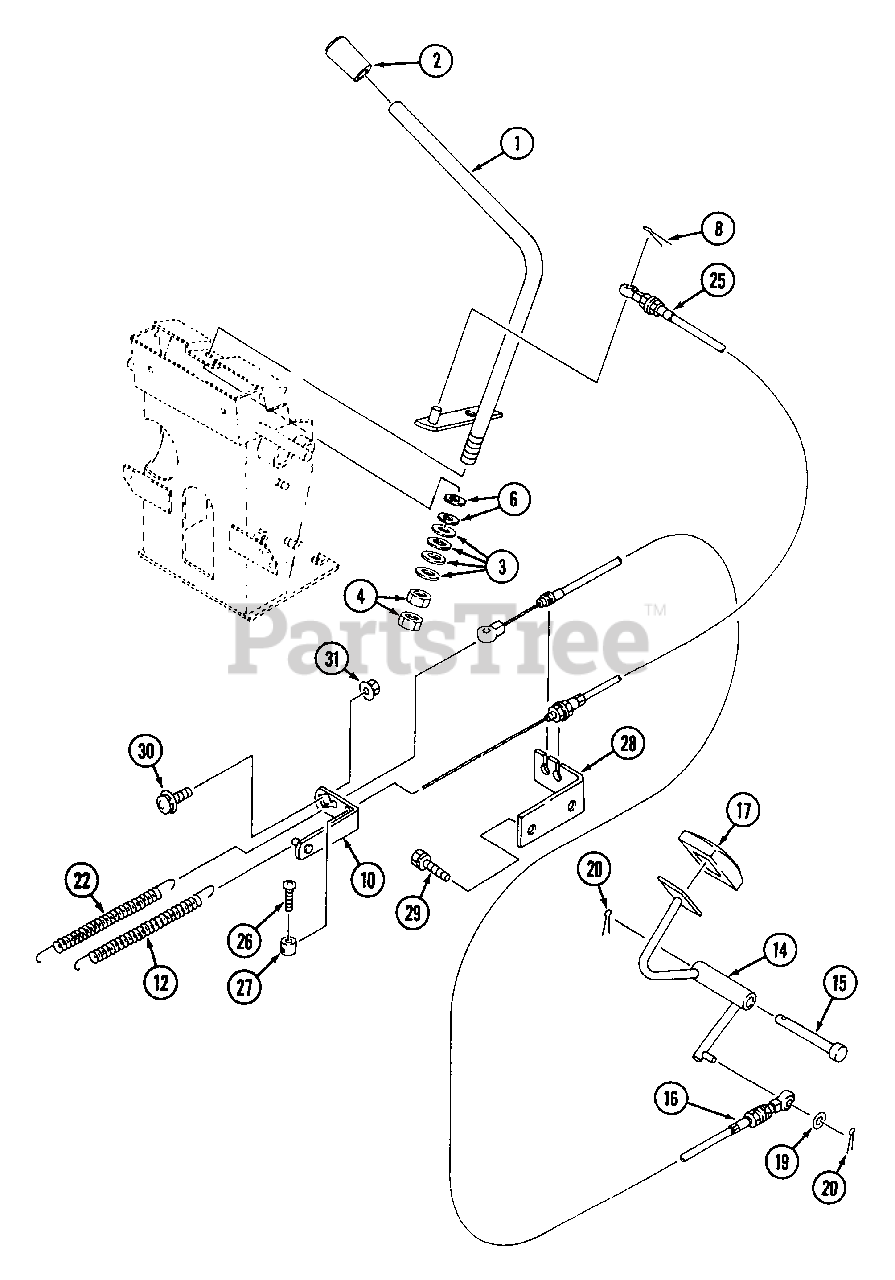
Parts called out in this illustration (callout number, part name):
1	Lever, Accelerator
8	Pin Split
14	Pedal, Accelerator
15	Pin
16	Wire, Accelerator
17	Cover Pedal
19	Washer
20	Pin Split
22	Spring
25	Wire, Accelerator
